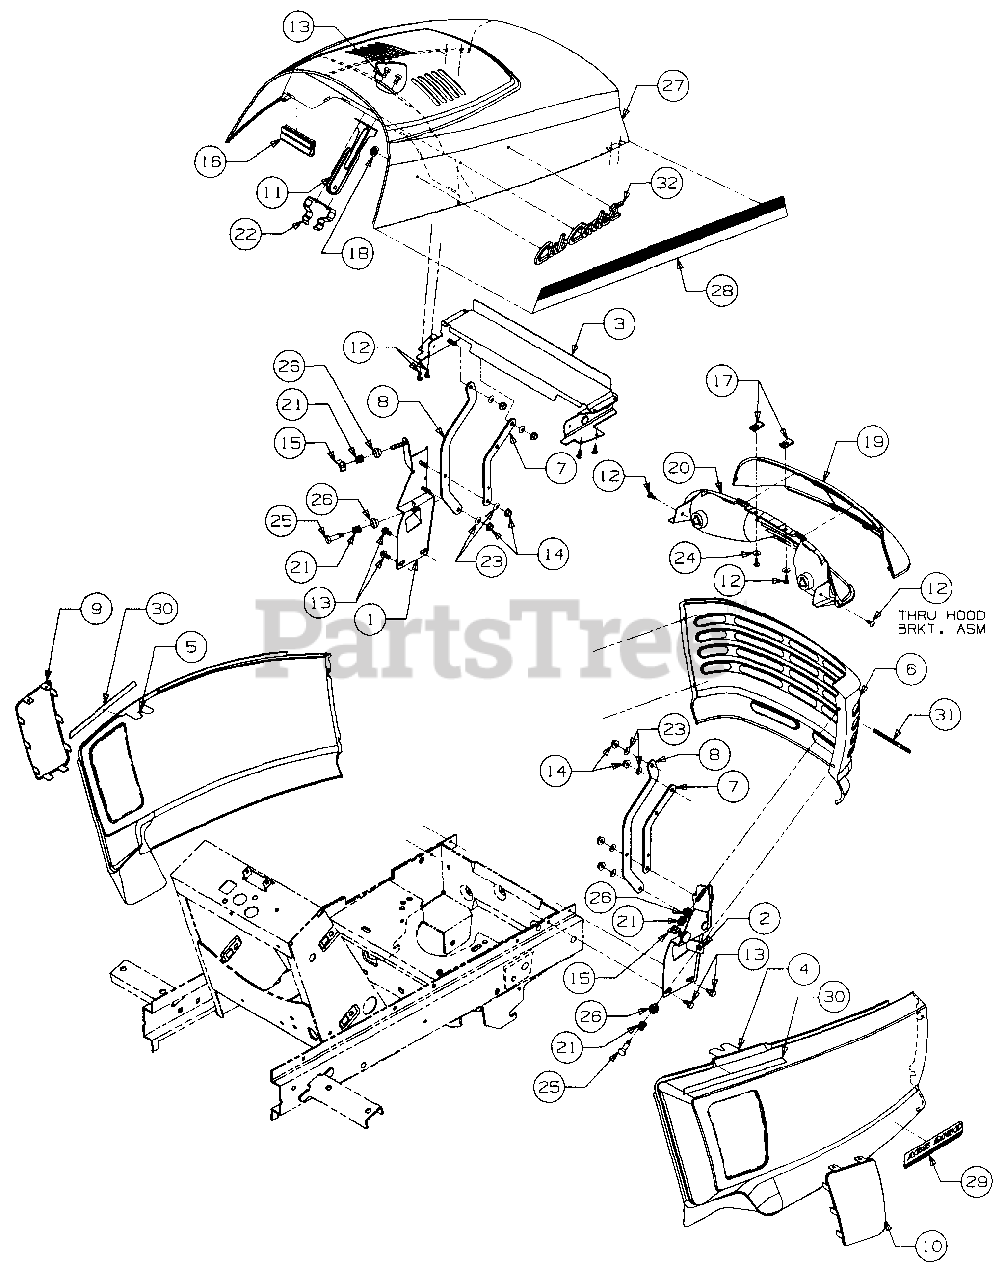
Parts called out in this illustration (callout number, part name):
1	Bracket, Grille LH
2	Bracket, Grille RH
3	Bracket, Upper Hood
4	Panel, RH Side
5	Panel, LH Side
8	Link, Long Hood
9	Screen, LH Panel
10	Screen, RH Panel
11	Guide, Hood
12	Screw, Truss Mach Tapp, #10 x .50
13	Screw, Hex Wash Hd Tapp, 1/4 x .50
14	Nut, Hex Flange Lock, 1/4-20
15	Nut, Wing, 1/4-20
16	Seal, Heat Baffle
17	Nut, U-Type Speed, #10
18	Retainer, Push Nut
19	Headlight Assembly
20	Reflector, Headlight
21	Spring, Compression, .50 OD x .50 Lg
22	Spring, Hood Latch
23	Washer, Spring, .265 x .562 x .025
24	Washer, Flat, .218 x .62 x .063
25	Bolt, Shoulder, .31 Dia x .75 Lg
26	Bushing, Tapered
27	Hood, Series 2000
28	Graphic, Hood, RH
29	Graphic, HDS 2165
30	Strip, Protective
31	Graphic, Warning HOT
32	Script w/Studs, Cub Cadet
